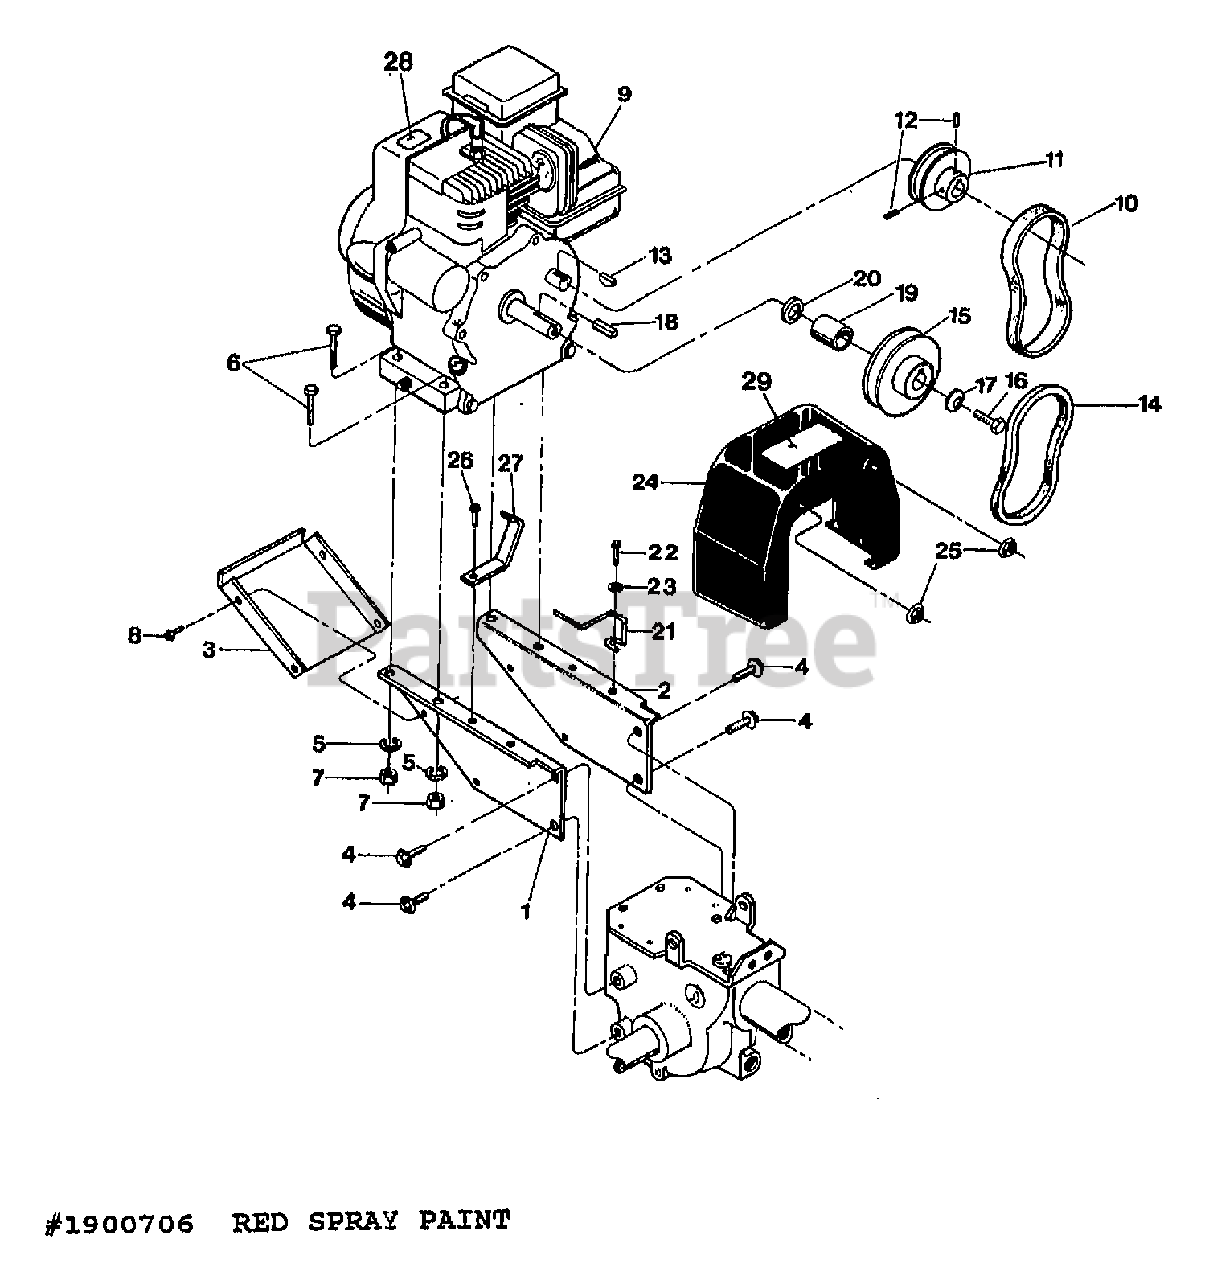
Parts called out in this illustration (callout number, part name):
1	BRKT-ENG LT P4
2	BRKT-ENG RT PNT
3	PAN-ENG BRKT PNT
4	SCR-HFLK 5/16-18X.75 ZP
5	WASHER-LK .312 ZP
6	SCR-HH 5/16-18X1.5 G5 ZP
7	NUT-HEX 5/16-18 ZP
8	SCR-HW M10-32X.5 THRD ROLL
8	SCR-HH SEMS 10-32 X .5 ZP (EARLY UNITS)
9	ENGINE,B&S 5HP STANDARD RECOIL WITH MAGNETRON MODEL 130292 TYPE 3220-01
9	ENGINE,B&S 5HP ELEC. START WITH MAGNETRON MODEL 130297 TYPE 3221-01
10	BELT-FLAT (SEE BELT SET BELOW)
11	PULLEY-REV DRILL/TAP
12	SCR-SS 1/4-20 X .25 (SECURES REVERSE ENGINE PULLEY)
13	KEY-WOODRUFF #5
14	BELT-V GROOVE FWD SMFRAME (SEE BELT SET BELOW)
15	PULLEY-ENGINE MACH
16	SCR-HH 5/16-24X.75 G5 ZP
17	WASHER-.827X.331X.098 (CONCAVE SURFACE FACES FORWARD PULLEY)
18	KEY-.188 SQX1.0
19	SPACER-.938X.755X1.19 (ON FORWARD PTO SHAFT BETWEEN ENGINE & FORWARD PULLEY)
20	SHIM-1.0X.7656X.031 (ON FORWARD PTO SHAFT BETWEEN ENGINE & SPACER)
21	GUIDE-BELT FWD
22	SCR-HWH 1/4-20 X .75 STH
23	WASHER-FLAT 1/4 SAE
24	COVER-BELT W/DECAL (INCL. 29)
25	NUT-HFLK 5/16-18 ZP
26	SCR-HWH 1/4-20 X .5 STH
27	GUIDE-BELT REV PNT
28	DECAL-STABIL STARTING
29	DECAL-BELT COVER OPC
